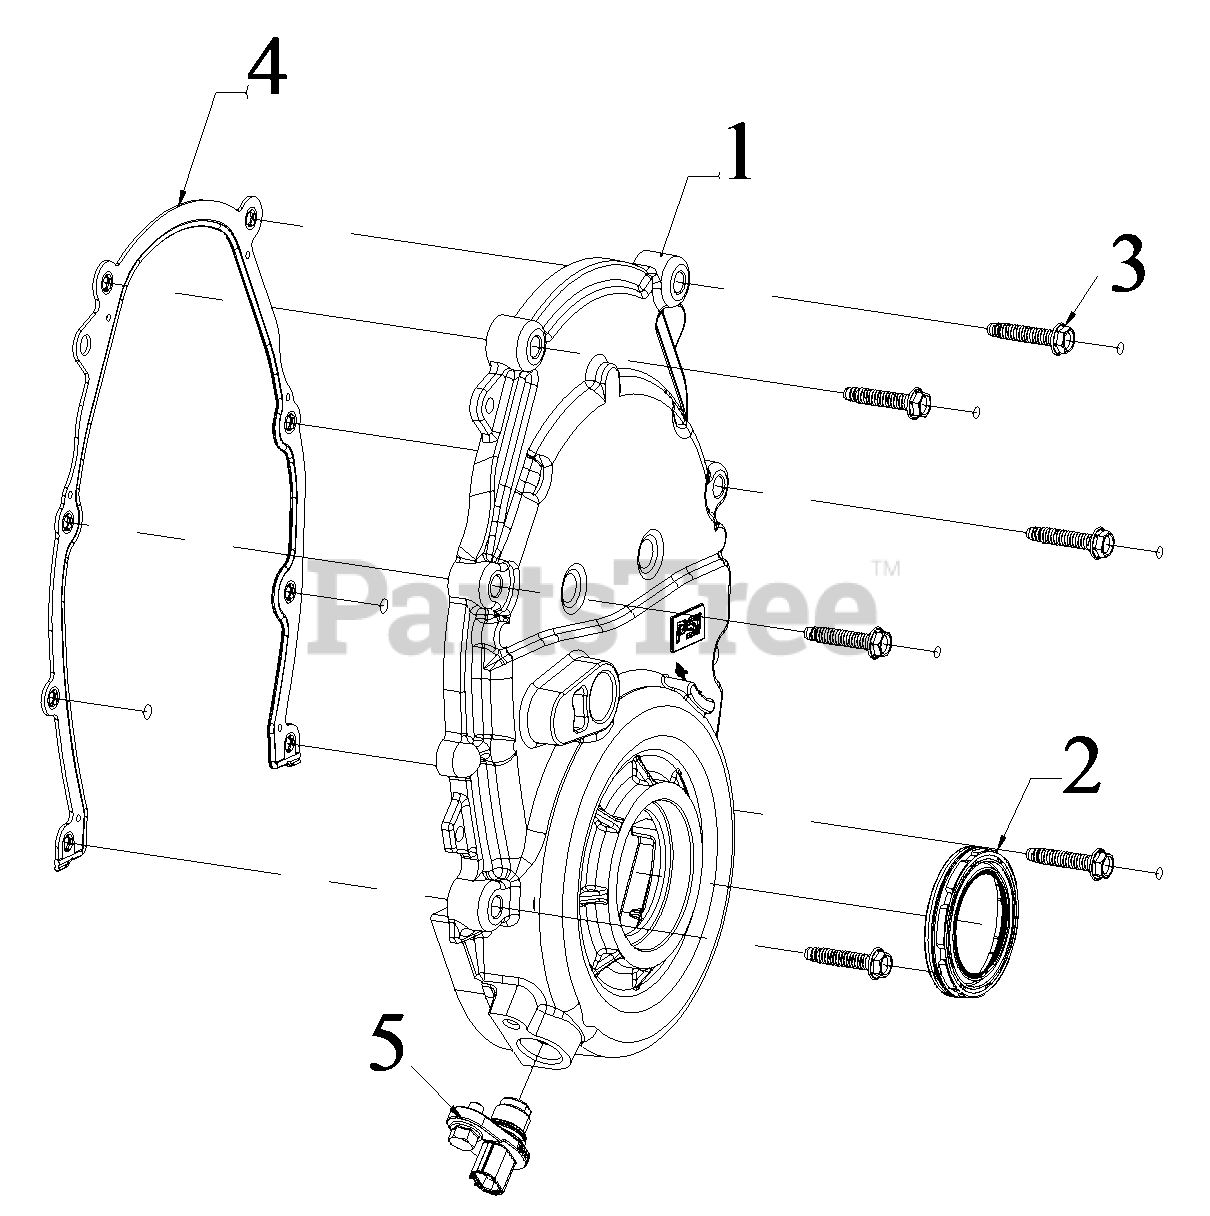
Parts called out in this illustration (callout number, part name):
1	COVER, FRONT COVER
2	SEAL, ENGINE FRONT COVER
3	BOLT, ENGINE FRONT COVER
4	GASKET, ENGINE FRONT COVER
5	SENSOR, CRANKSHAFT
